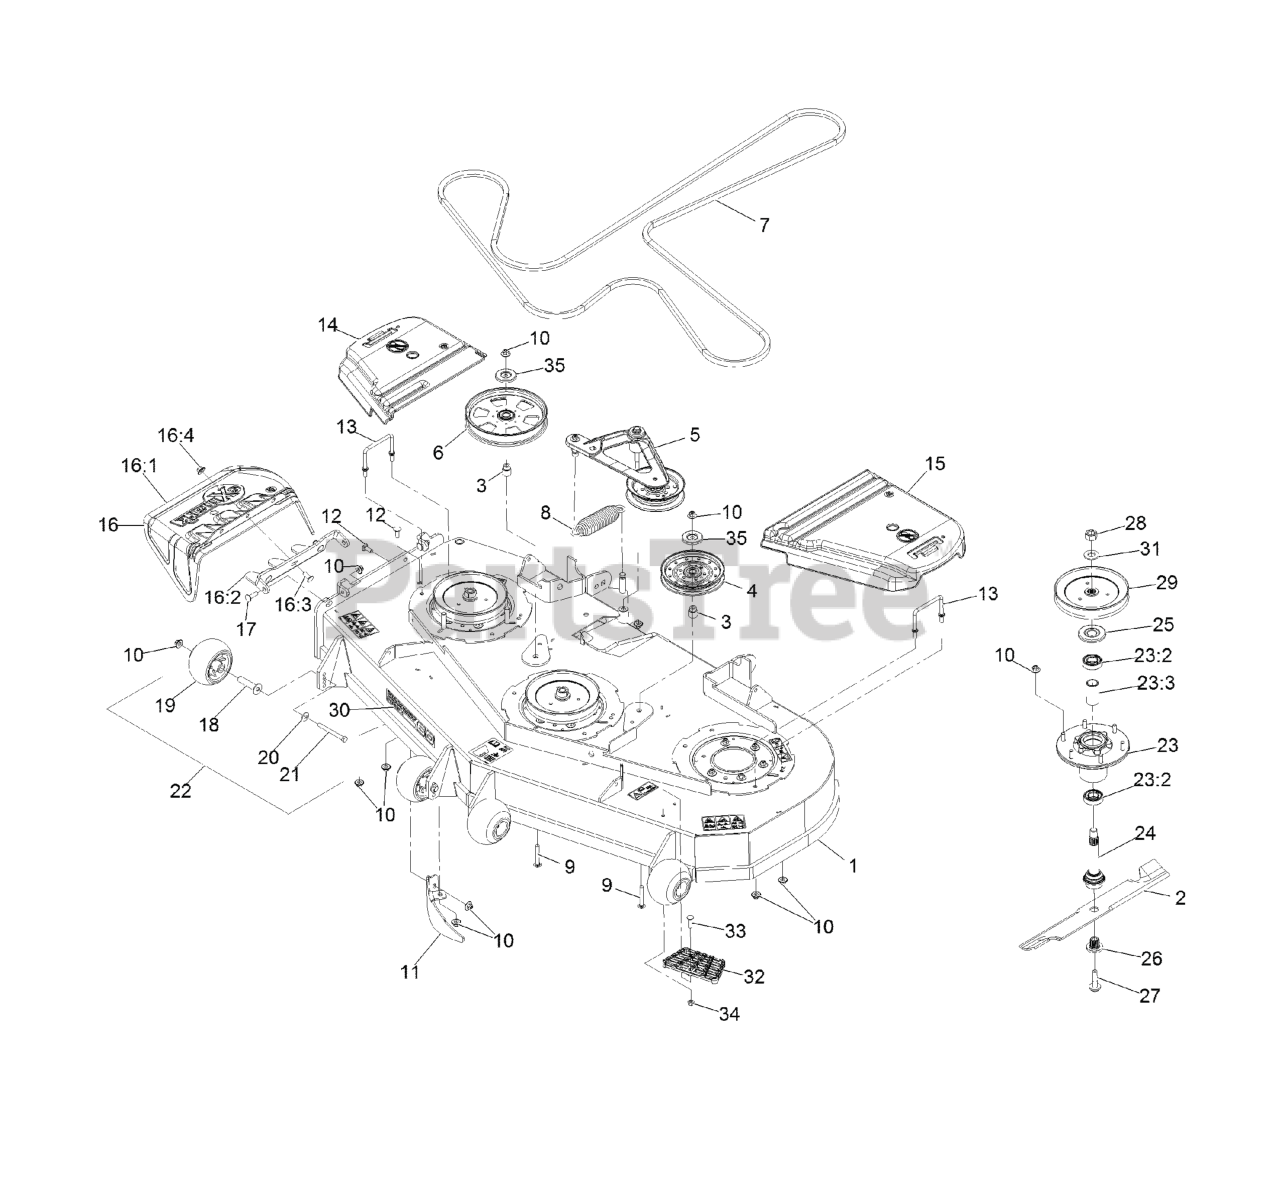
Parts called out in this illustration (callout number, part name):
1	DECK ASM,W/DECALS 60
2	Blade-Extreme 2, 20.50"
3	BUSHING-IDLER
4	IDLER-PULLEY
5	DECK IDLER ASM
6	PULLEY-IDLER, FLAT
8	SPRING-EXTENSION
9	SCREW-CARR
10	Nut-Nyloc 3/8-16 Flg
11	DOGLEG - LZ60
12	SCREW-CARR
13	WIREFORM-COVER
14	COVER-BELT, RH
15	COVER-BELT, LH
16	ASM,DISCHARGE CHUTE
16:1	CHUTE,DISCHARGE
16:2	BRACKET,DISCHARGE CHUTE
16:3	SCREW-CARR
16:4	Nut-Nyloc 3/8-16 Flg
17	Bolt-Carriage 3/8-16 X 1 1/4
18	AXLE, ROLLER
19	ROLLER-SCALP, ANTI
20	WASHER-BELLEVILLE
21	SCREW-HH 3/8-16 X 3 3/4 GR 8
22	KIT, ANTI-SCALP ROLLER
23	ASM-CUTTER HSG WITH BEARINGS
23:2	BEARING-BALL
23:3	SPACER-BEARING
24	ASM-SPINDLE AND SEAL
25	GUARD,BEARING TOP .989
26	BUSHING,SPLINED
27	SCREW,SEMS 1/2-20 X 2.19
28	NUT-HEX
29	SHEAVE,BLADE DRIVE 7.25
30	DECAL, 604
32	STEP-DECK
33	Bolt-Carriage 5/16-18 X 1 1/4
34	NUT-HF, NI
35	SHIELD-DUST
